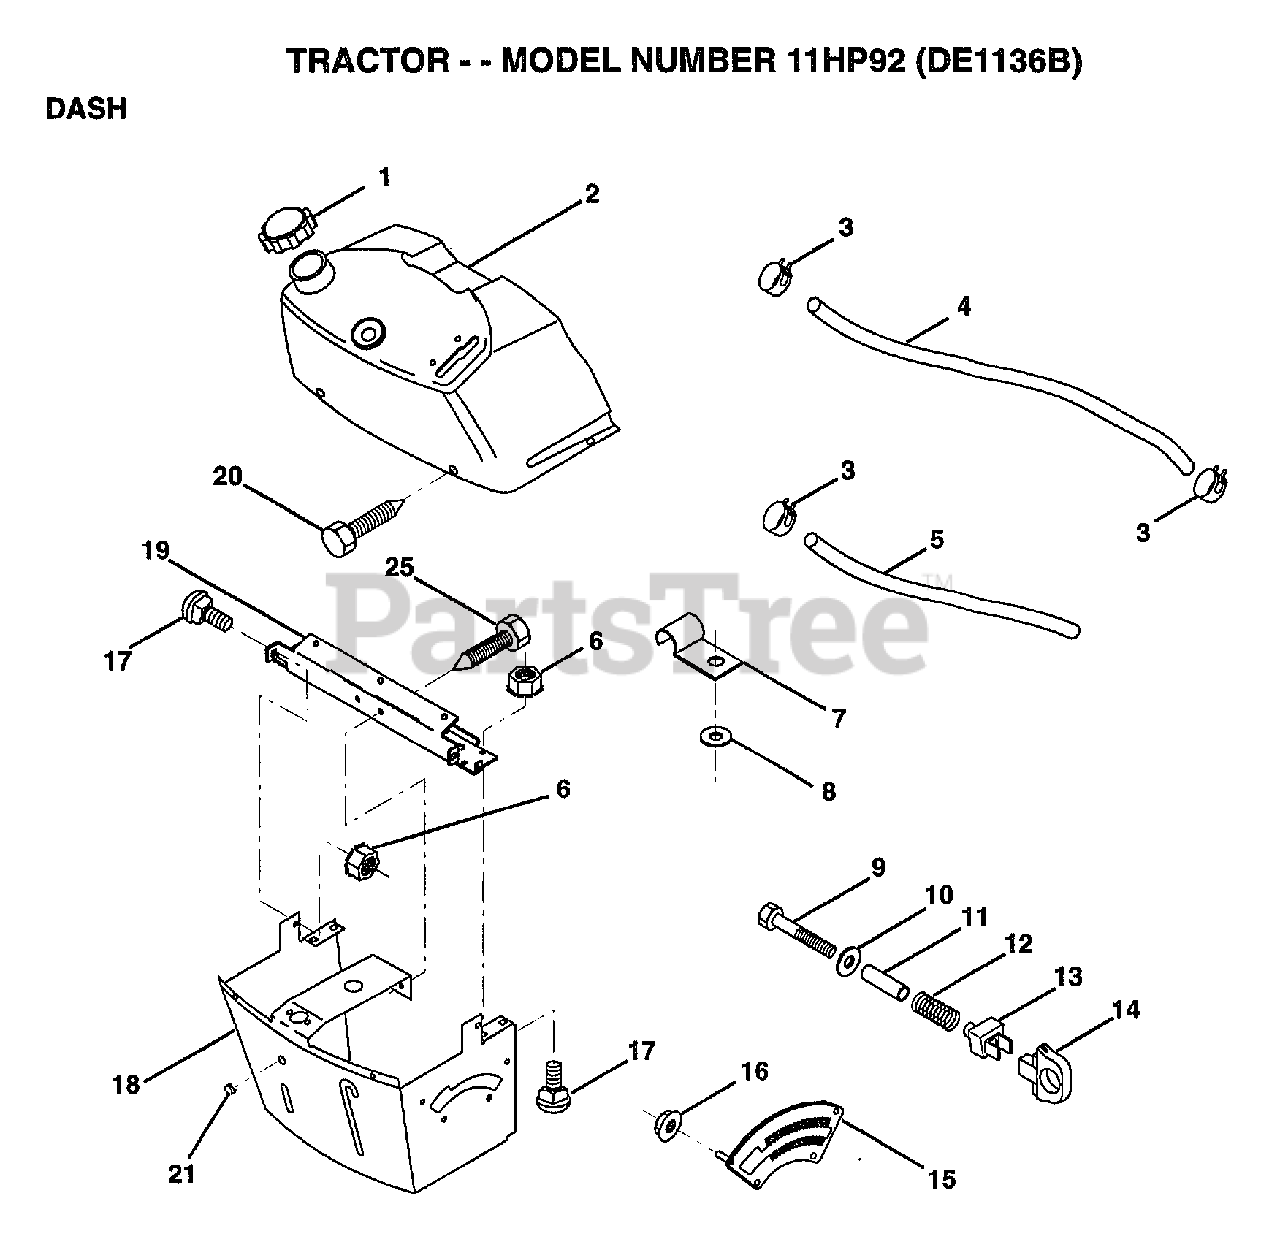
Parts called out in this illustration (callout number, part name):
1	CAP BLK FUEL LR
2	TANK.ASM.DASH.LR
3	HOSE CLAMP
5	FUEL LINE T
6	NUT HXKEP 1/4X20
7	CLIP T
8	WASHER PM
9	BOLT
11	SPACER SPLIT
12	SPRING M
13	"KNOB,HGT RETAINER"
14	KNOB
15	ADJUSTER QUAD
16	NUT
17	BOLT
18	SUPT ASSY DASH
19	CROSS BRACE
20	SCREW.1/4-20X1/2
21	PLUG DOME
25	SCREW LT
